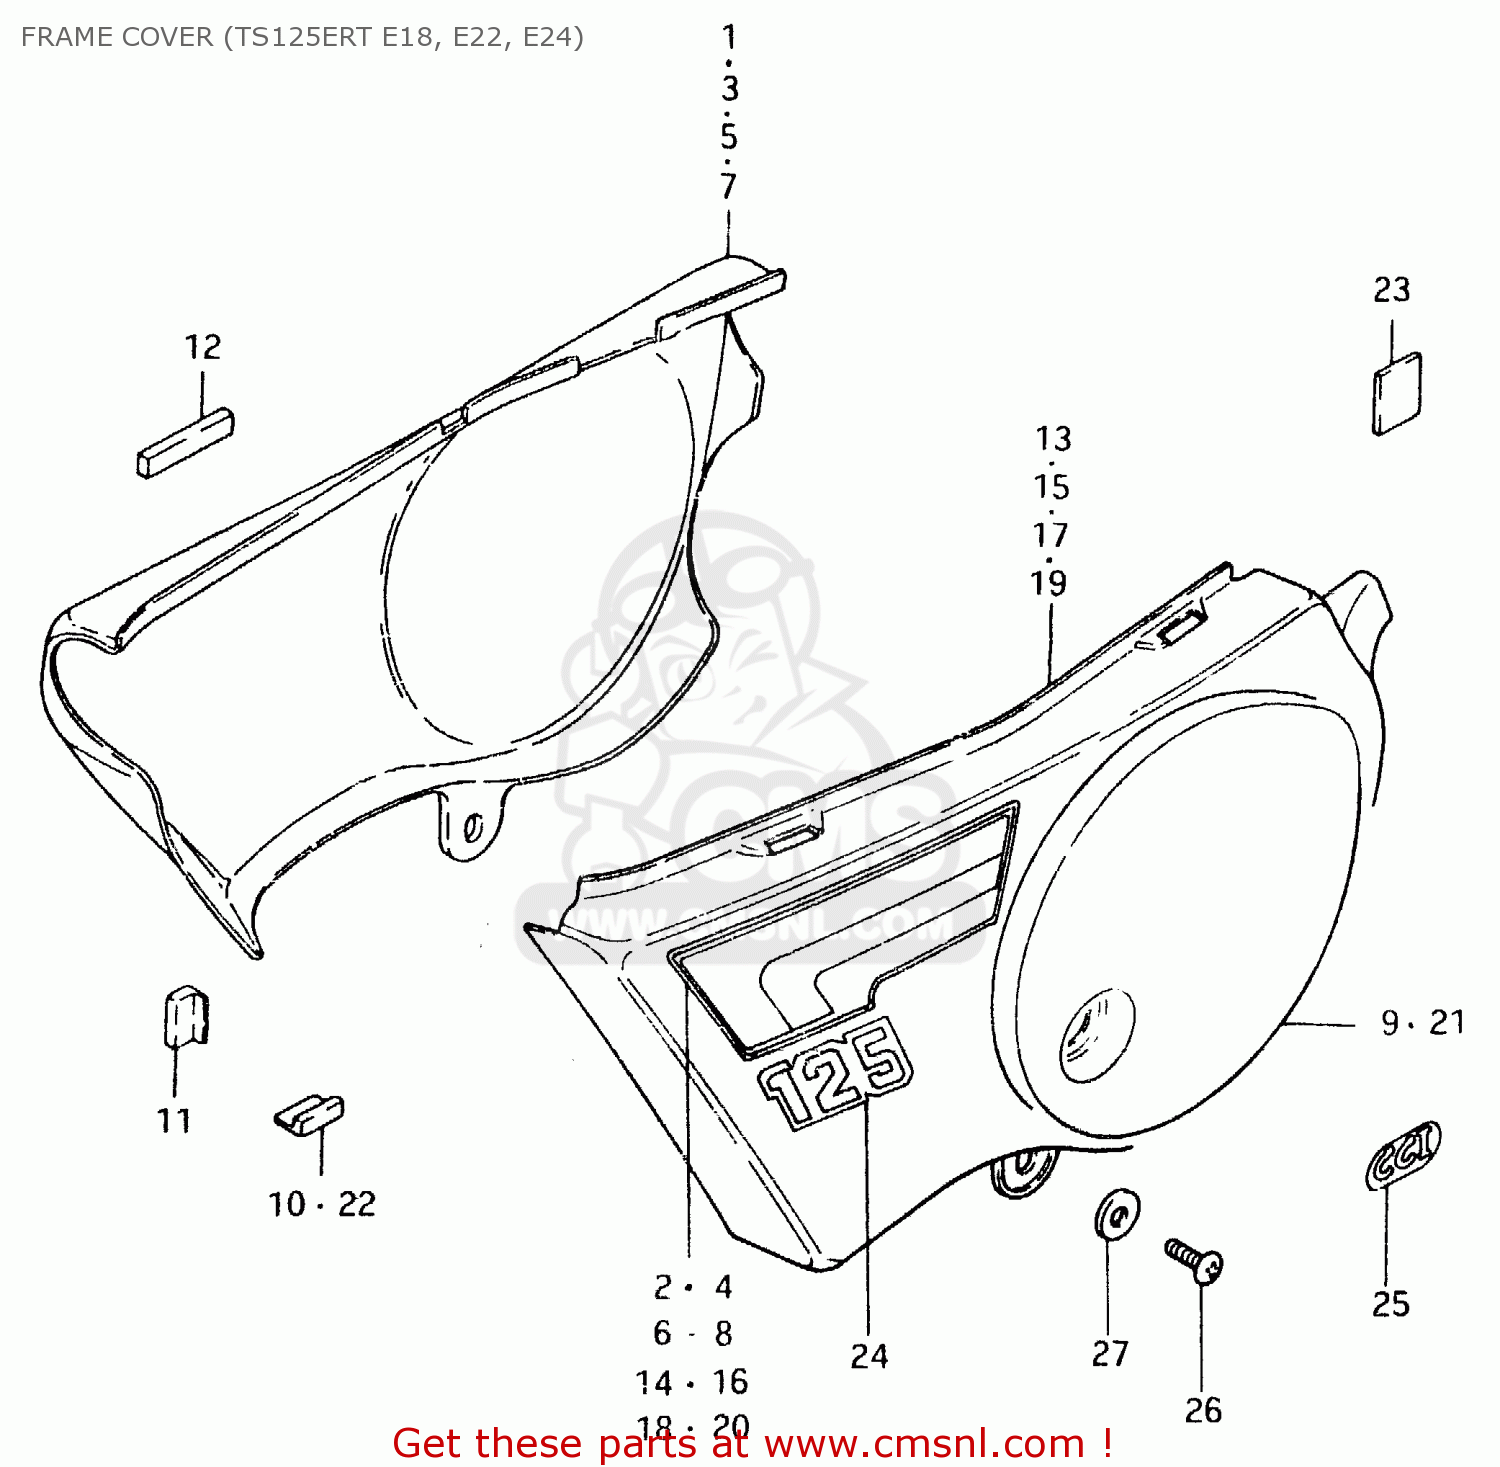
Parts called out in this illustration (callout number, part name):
1	COVER, FRAME RH (RED)
2	TAPE, RH
3	COVER, FRAME RH (WHITE)
4	TAPE, RH
5	COVER, FRAME RH (BLUE)
6	TAPE, RH
7	COVER, FRAME RH (YELLOW)
8	TAPE, RH
9	EMBLEM, RH
10	CUSHION,FRAME COVER
11	CUSHION,FRAME COVER
12	CUSHION,FRAME COVER
13	COVER, FRAME LH (RED)
14	TAPE, LH
15	COVER, FRAME LH (WHITE)
16	TAPE, LH
17	COVER, FRAME LH (BLUE)
18	TAPE, LH
19	COVER, FRAME LH (YELLOW)
20	TAPE, LH
21	EMBLEM, LH
22	CUSHION,FRAME COVER
23	PROTECTOR(170X95X3.0)
24	EMBLEM, "125"
25	EMBLEM,CCIS
26	SCREW 6X12
27	WASHER
